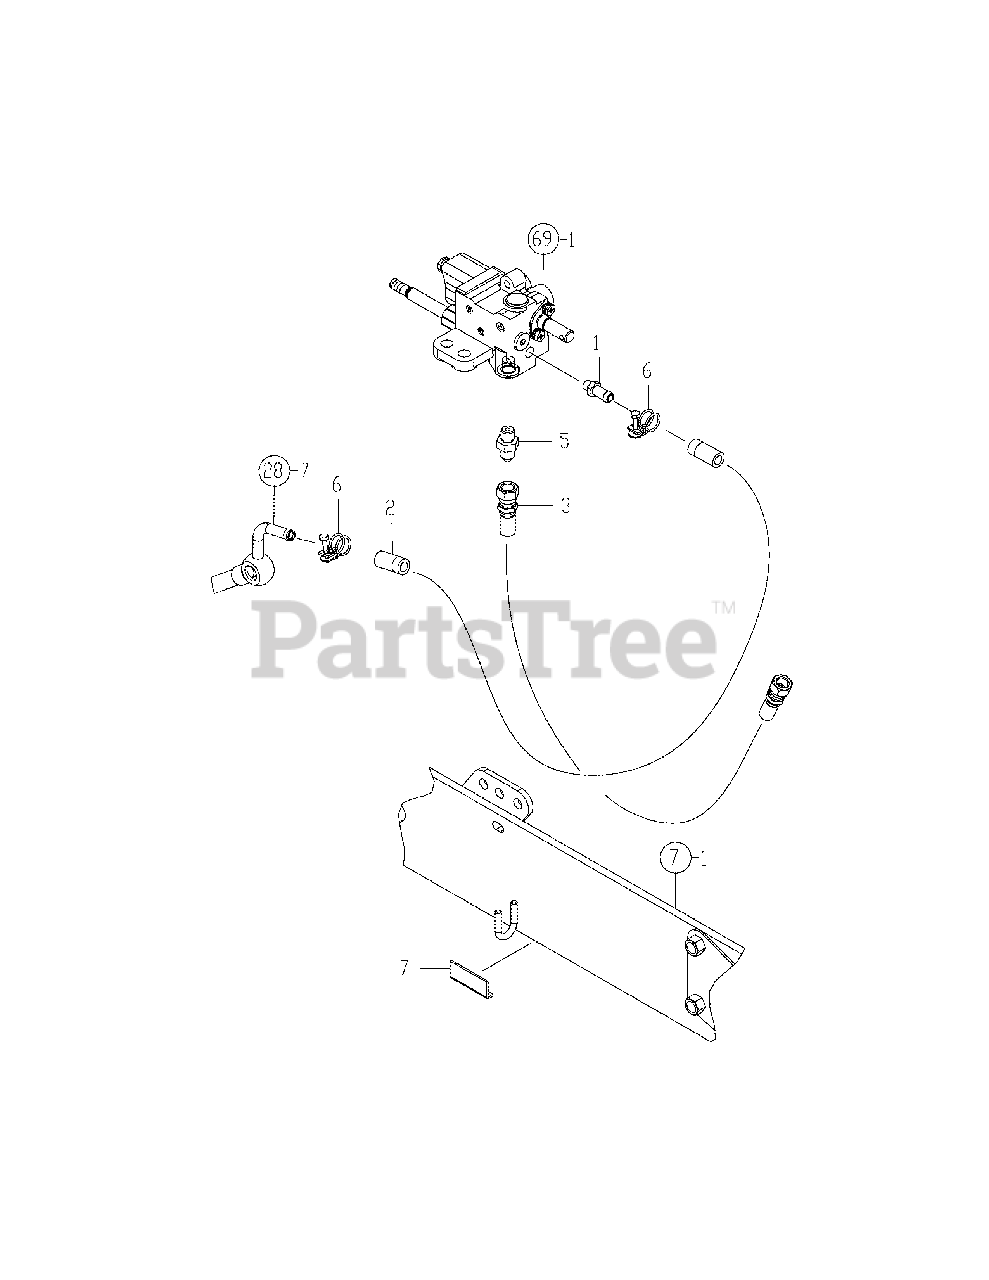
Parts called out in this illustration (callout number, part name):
2	Lp Hose, Drain
2-1	Lp Hose, Drain
3	Hp Hose, Clynder
5	Connector Pf1/4
6	Clamp, Hose 18
